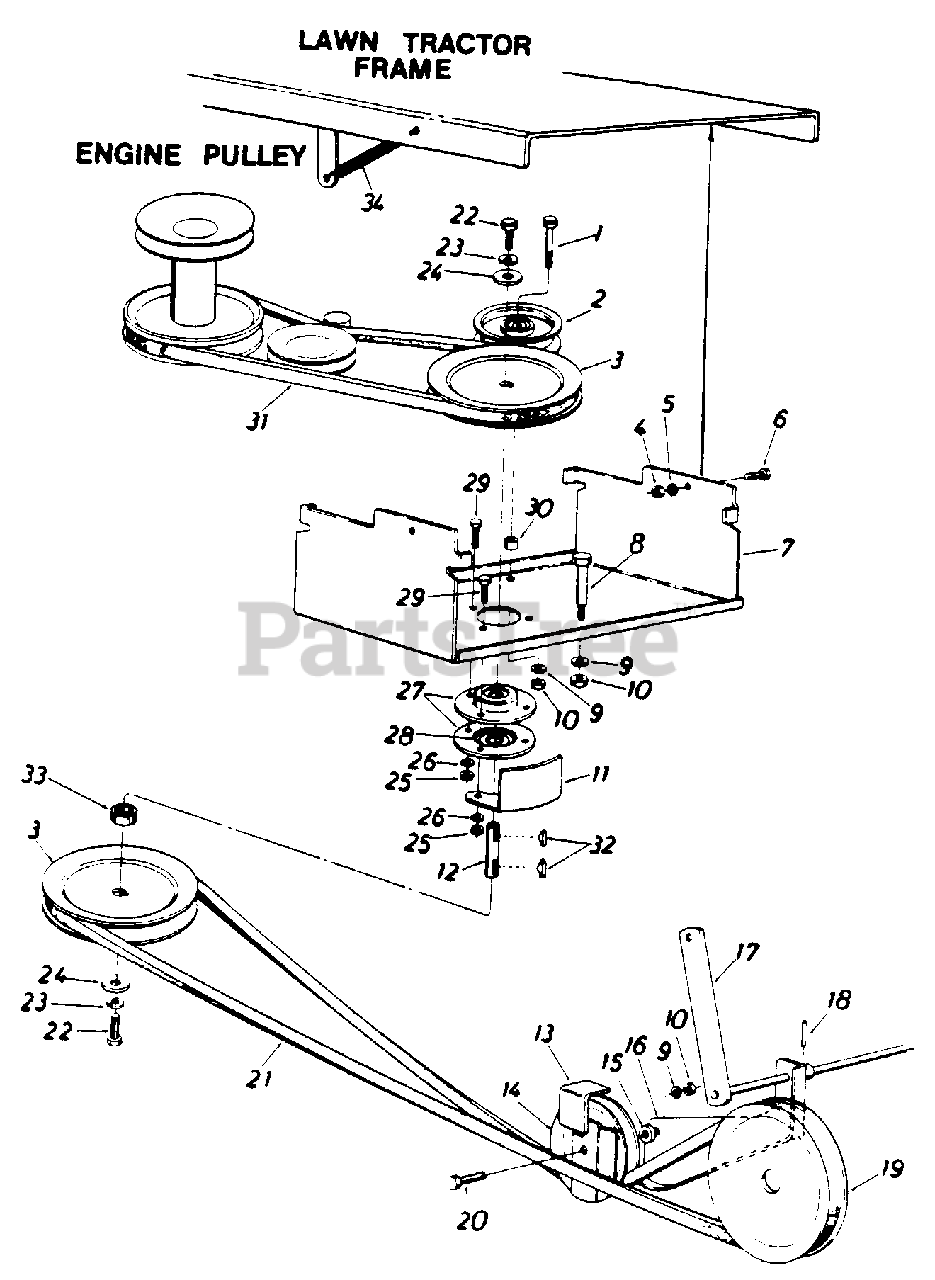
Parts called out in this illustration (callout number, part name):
1	Hex Bolt 3/8-16 x 2n Lg.
2	FL-ldler w/Flange 3-3/4" O.D.
3	5/8" "V"-Pulley .79" I.D. x .65" O.D.
4	Hex Nut 3/8-24 Thd.
5	L-Wash. 3/8" I.D.
6	Hex Bolt 3/8-24 x .88" Lg.
7	Carriage Bracket
8	Shoulder Bolt .498" Dia.
9	L-Wash. 318" I.D.
10	Hex Nut 3/8-16 Thd.
11	Belt Guard
12	Shaft .787" Dia. x 3.21" Lg.
13	Belt Separator Plate
14	Fl-ldler w/Flanges 3.25"
15	Fl-Wash. .406 I.D. x 1.25n
18	Spring Pin Roll 3/16" Dia.
19	5/8" V-Pulley 1.50n l.D. x 6 5n O.D.
20	Hex Bolt 3/8-16 x 1.75" Lg.
21	V-Belt
22	Hex Bolt 5/16-18 x .88n Lg. Spec.
23	L-Wash. 5/16" l.D.
24	Fl-Wash. 344" l.D. x 1.125"
25	Hex Nut 5/16-18 Thd.
26	L-Wash. 5/16" l.D.
27	Bearing Housing 1.85" l.D.
28	Ball Bearing 1.85" O.D.
29	Hex Sems Bolt 5/16-18 x .75"
30	Spacer
32	Hi-Pro Key 3/16" x 5/8"
33	Spacer .66" l.D. x 1" O.D.
34	Extension Spring
